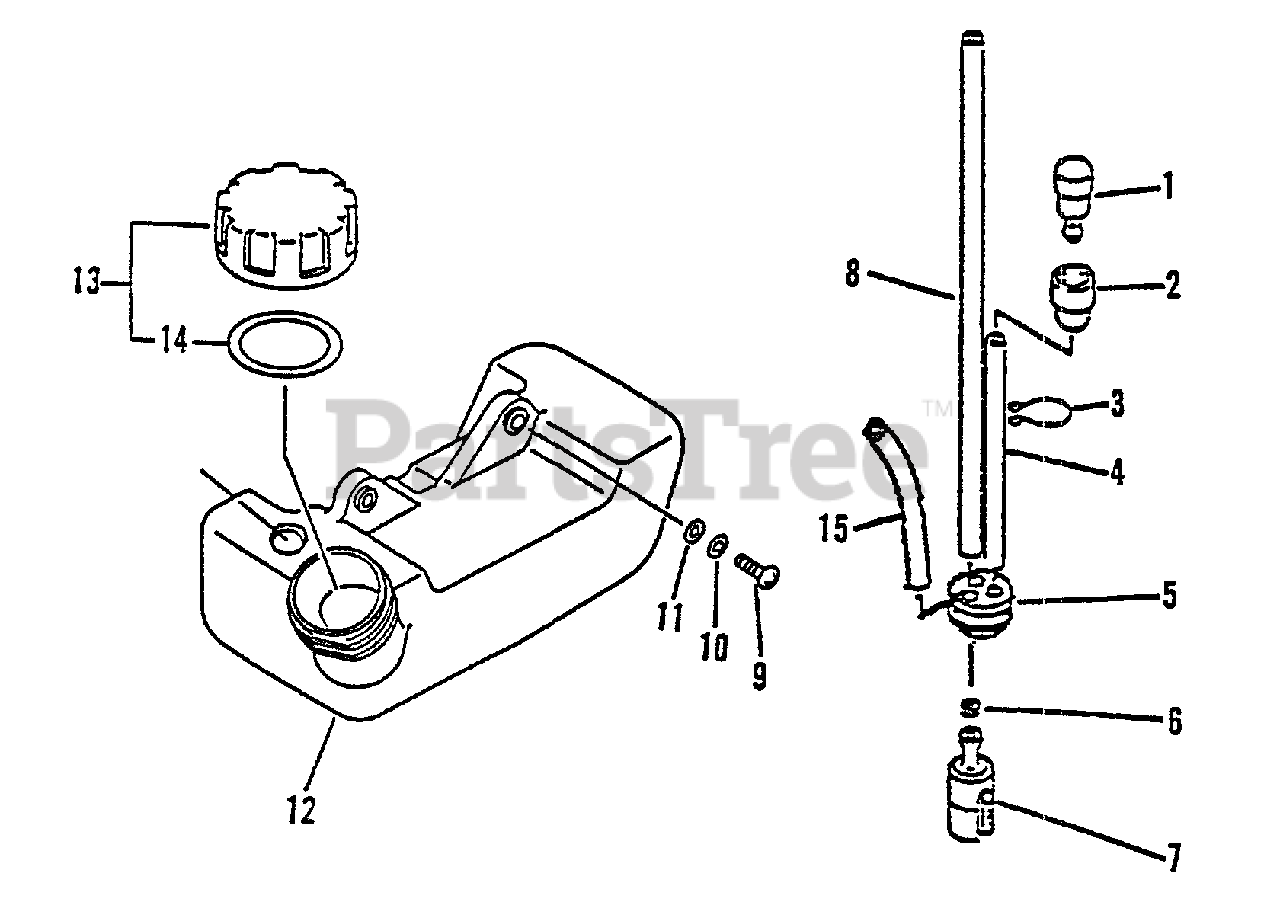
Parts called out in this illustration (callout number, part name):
1	VENT ASSY
2	HOLDER, VENT
3	CLIP, TUBE
4	PIPE, FUEL 3x-5x-70 BLACK
5	GROMMET, FUEL
6	CLIP 6 MM
7	FILTER, FUEL
8	PIPE, FUEL 3x-5x-180
9	SCREW 5×16
10	WASHER, SPRING 5
11	WASHER 5.5×12×0.8
12	TANK, FUEL
13	CAP ASSY
14	GASKET, FUEL CAP
15	PIPE, FUEL RETURN 3×6×90 MM CLEAR
